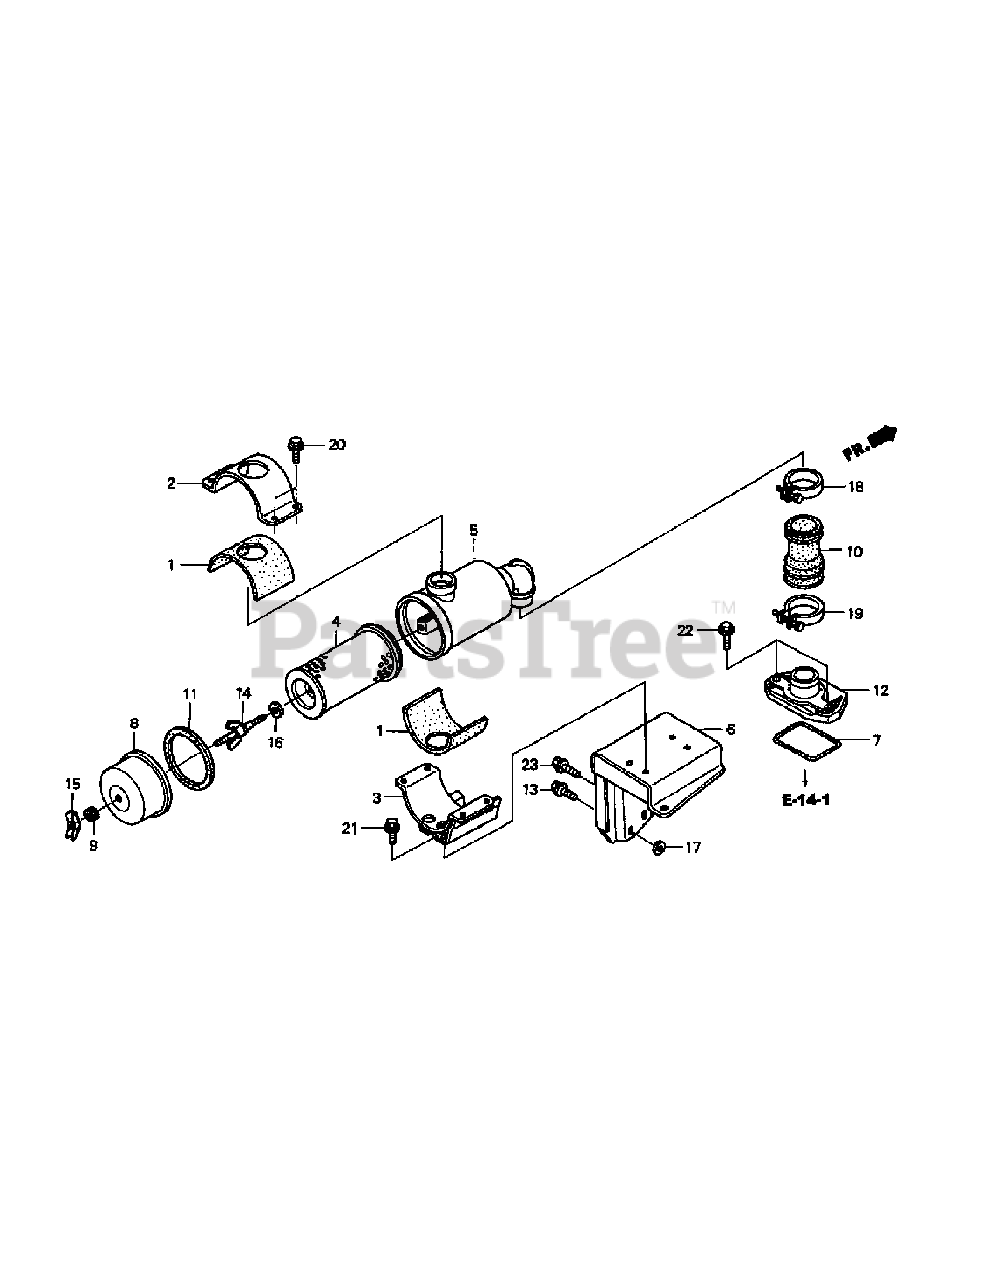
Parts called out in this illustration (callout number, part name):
1	Air Cleaner Holder Rubber
2	Air Cleaner Holder (Upper)
3	Air Cleaner Holder (Lower)
4	Air Cleaner Element
5	Air Cleaner Housing
6	Air Cleaner Bracket
7	Air Cleaner Housing Seal
8	Air Cleaner Cover Assy.
9	Air Cleaner Grommet
10	Air Cleaner Connecting Tube
11	Air Cleaner Seal
12	Connecting Tube Joint
13	Flange Bolt (6x14)
14	Air Cleaner Bolt
15	Wignut (6mm)
16	Air Cleaner Washer
17	Seat Collar
18	Air Cleaner Connecting Clamp
19	Air Cleaner Connecting Clamp
20	Flange Bolt (6x14)
21	Flange Bolt (6x16)
22	Flange Bolt (6x28)
23	Flange Bolt (8x16)
